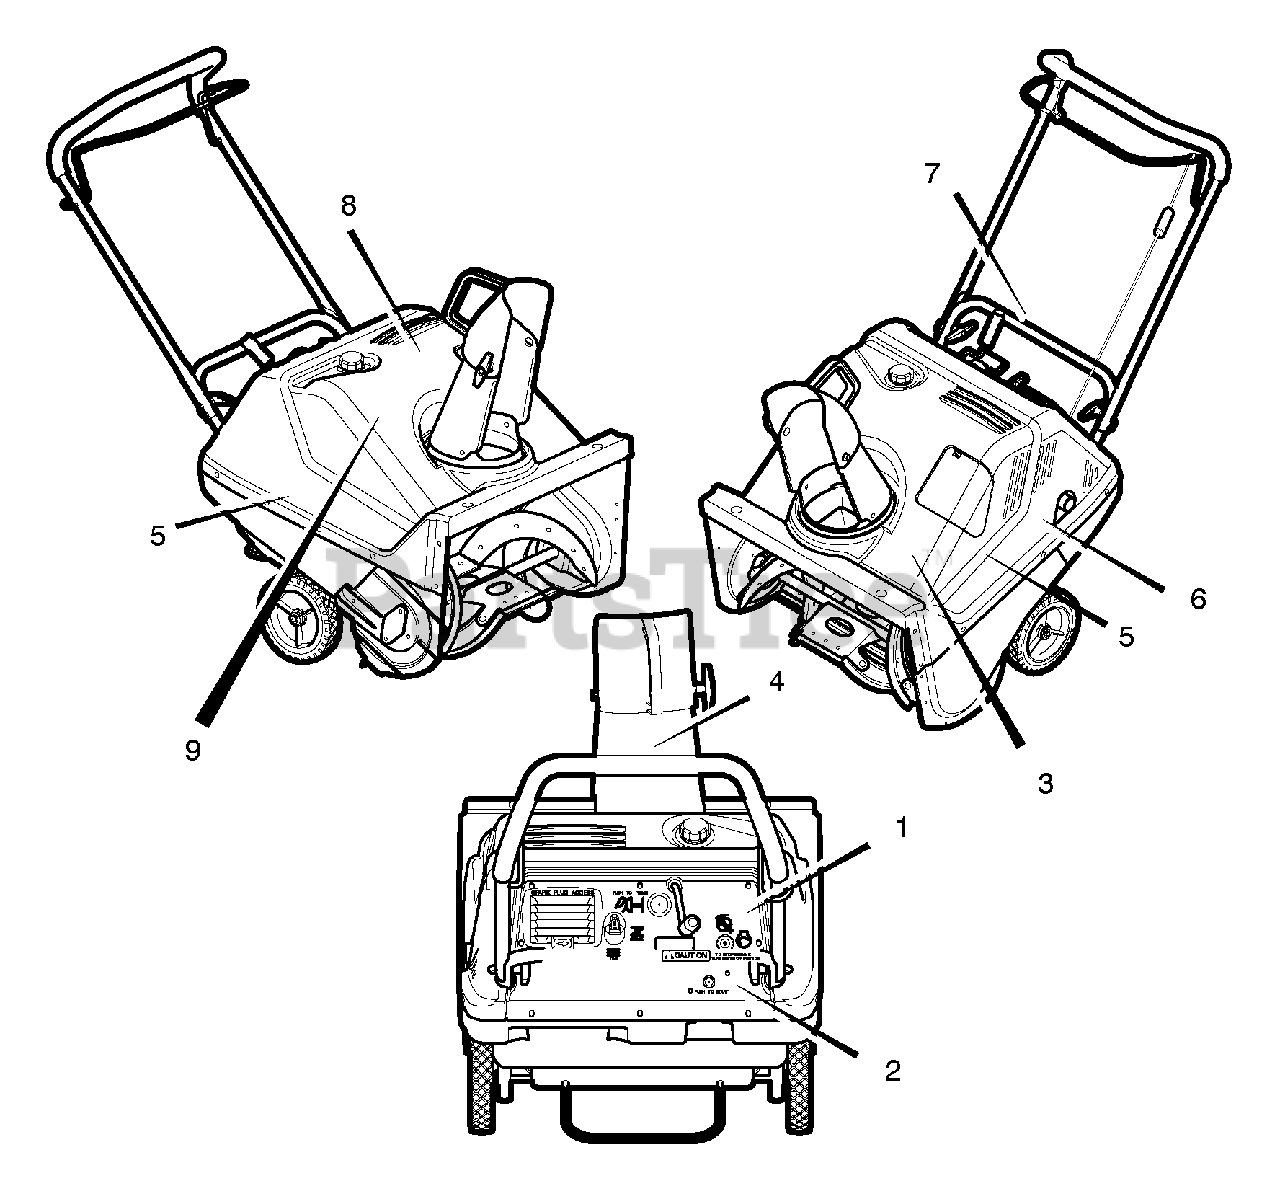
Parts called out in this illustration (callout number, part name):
1	Decal, Control Panel
2	Decal, Electric Start
3	Decal, Danger Auger
4	Decal, Danger Chute
5	Decal, STIGA
6	Decal, Hot Muffler
7	Decal, Auger Control
8	Decal, Snow Breeze
9	Decal, Briggs & Stratton
